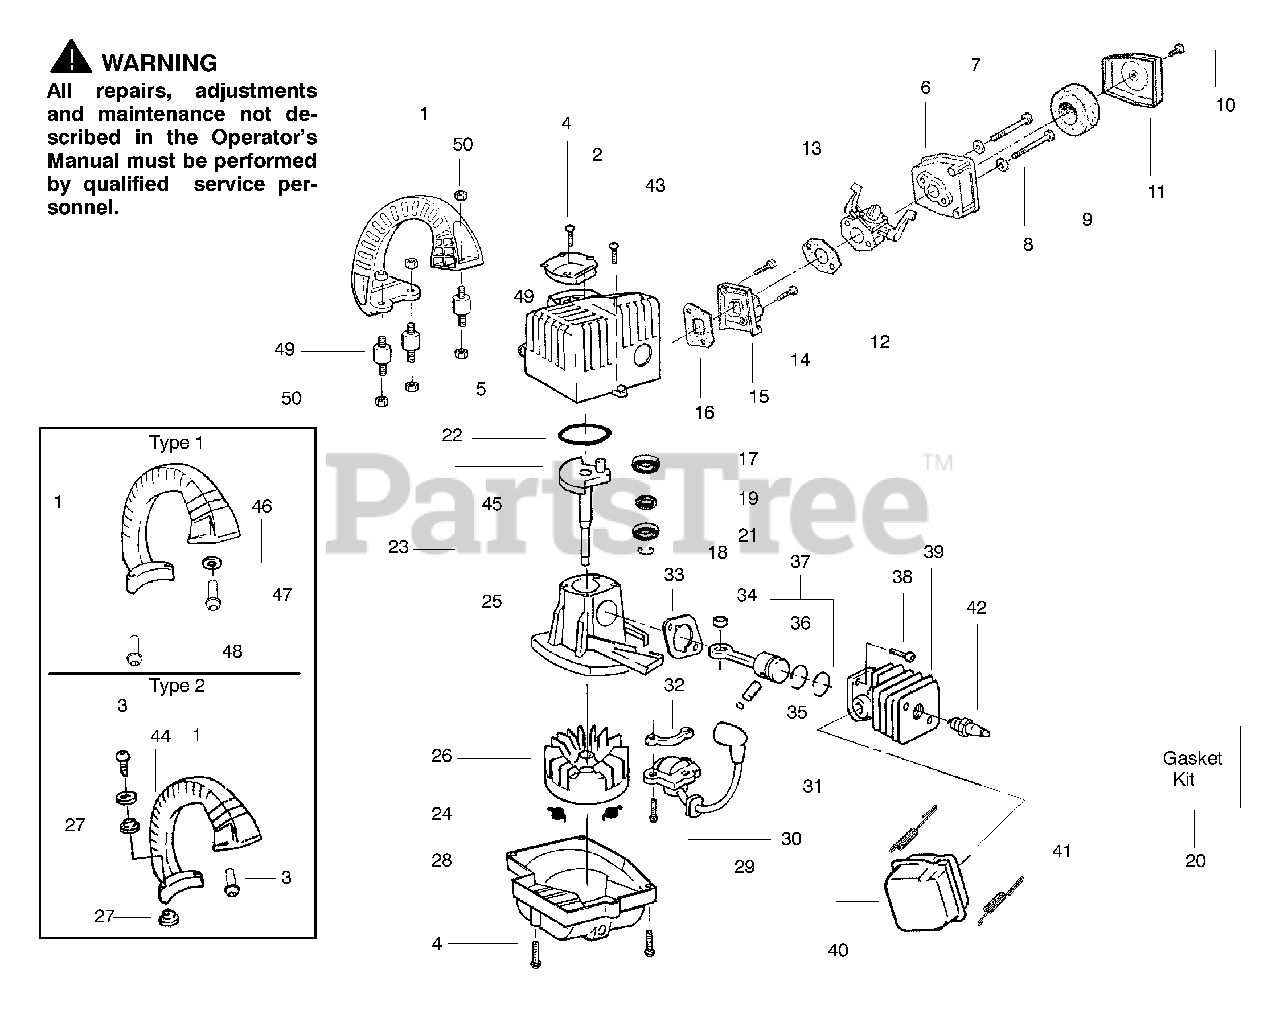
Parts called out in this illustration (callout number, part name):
1	Kit-Handle / Shroud Type 1,2,3
2	Plate Crankcase
3	Screw - Type 2
4	Screw
5	Kit-Shroud / Handle Type 1,2,3
9	Foam-Air Filter
11	Cover-Air Box Type 1
11	Cover-Air Box Type 2
12	Carburetor Ass'y. Kit Type 1 (WT501)
12	CarburetorAss'y. Kit Type 2,3 (WT557)
13	Gasket-Carb.
15	Carb. Adaptor
16	Gasket-Cyl/Carb. Adaptor
17	Inner Bearing
18	Retainer Ring (C'shaft)
19	Kit-Crankcase Seal
20	Gasket Kit
21	Outer Bearing
22	O-Ring-Gasket-C'case
23	C'case & C'shaft Ass'y.
24	Spring-Starter Dog
25	Crankcase Ass'y. Old Style
25	CrankcaseAss'y. New Style
26	Flywheel Ass'y.
27	Grommet-Rubber - Type 2
28	Fan Housing
30	Grommet-Ign. Module
31	Ignition Module
32	Spacer-Ign. Module
33	Gasket-Cylinder
34	Connecting Rod Ass'y.
35	Wrist Pin Retainer
36	Piston Ring
37	Piston Kit
39	Cylinder Kit
40	Kit-Muffler Ass'y.
41	Muffler Spring
42	Spark Plug (RCJ-6Y)
44	Washer - Type 2
45	Crankshaft Ass'y.
46	Washer-Flat - Type 1
47	Screw - Type 1
48	Screw - Type 1
49	Isolator - Type 3
50	Nut - Type 3
